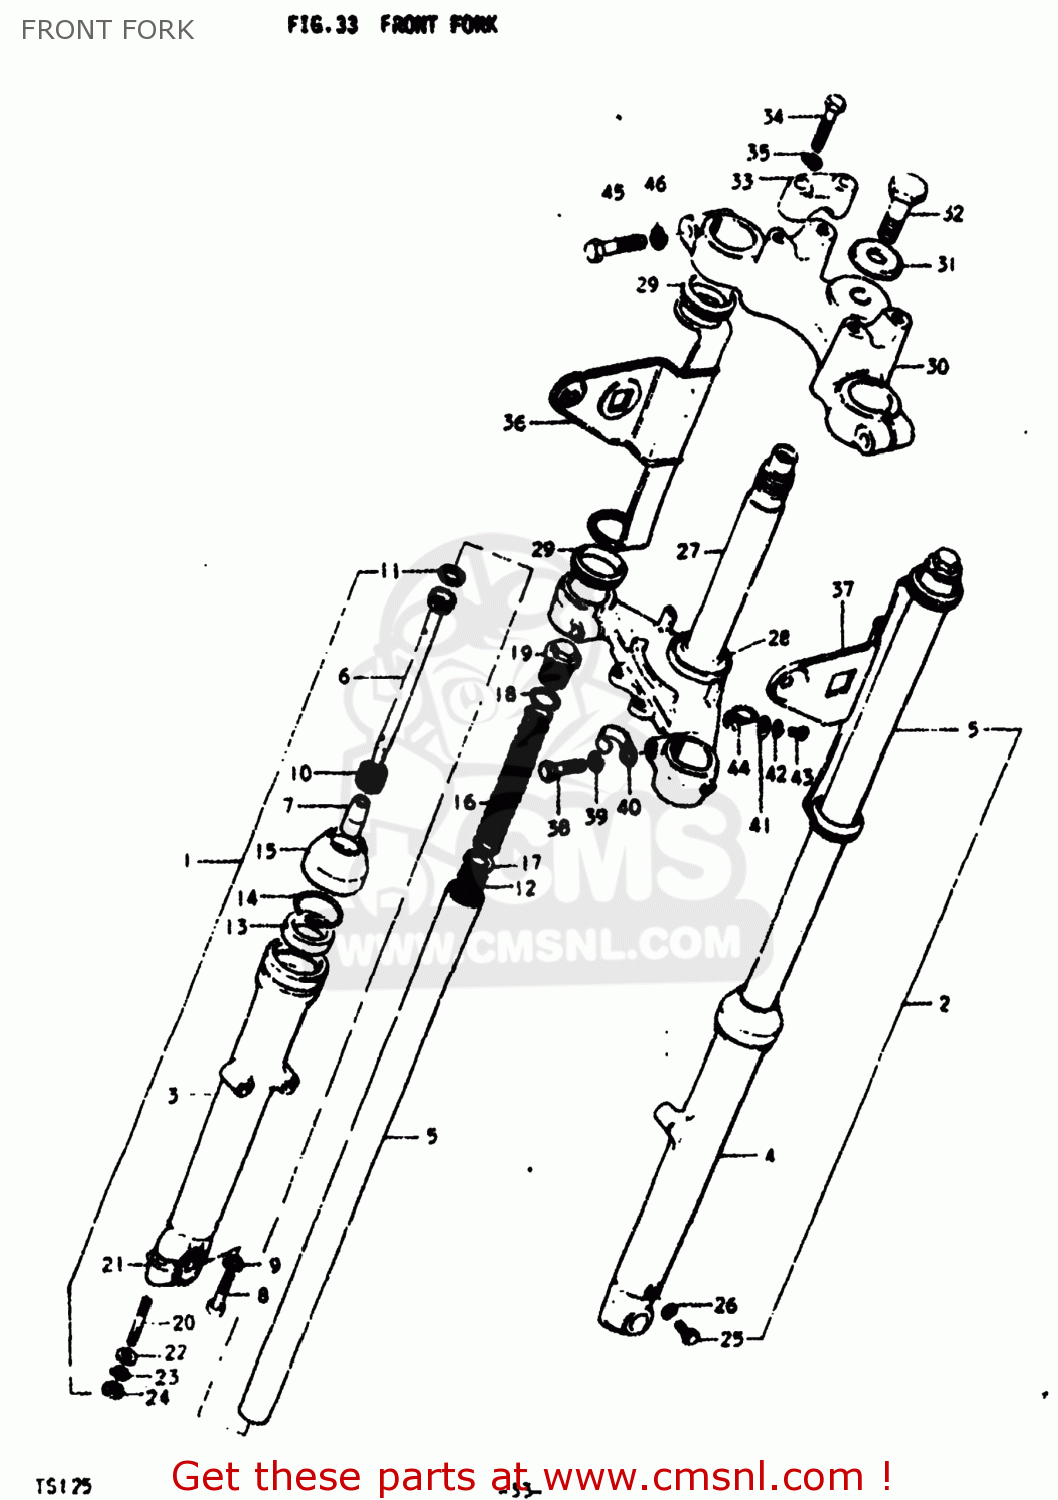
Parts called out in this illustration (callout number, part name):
1	DAMPER ASSEMBLY,RIGHT
2	DAMPER ASSEMBLY,LEFT
3	TUBE,FORK,OUTER,RIGHT
4	TUBE,FORK,LEFT,OUTER
5	TUBE,INNER
6	CYLINDER,FRONT FORK
7	PIECE,OIL LOCK
8	BOLT
9	GASKET (NAS)
10	SPRING,FORK REBOUND
11	RING
12	SPRING,FRONT FORK
13	OIL SEAL,FRONT FORK
14	CIRCLIP,FORK OIL SEAL
15	DUST SEAL,FRONT FORK
16	SPRING,FRONT FORK
17	SEAT,SPRING
18	O RING
19	BOLT,FORK
20	STUD 8X25
21	HOLDER,AXLE
22	WASHER
23	LOCK WASHER
24	NUT
25	BOLT(6X8)
26	GASKET,DRAIN,PLUG (NAS)
27	STEM,STEERING
28	RACE,STEERING OUTER LWR
29	CUSHION
30	HEAD,STEERING STEM(BLACK)
31	WASHER,STEERING STEM
32	BOLT,FORK INNER TUBE
33	HOLDER,HANDLE UPR
34	BOLT
35	LOCK WASHER
36	BRACKET,HEADLAMP,RIGHT
37	BRACKET,HEADLAMP,LEFT
38	BOLT
39	WASHER,LOCK 12
40	CLIP
41	WASHER
42	LOCK WASHER
43	SCREW 6X12
44	CLIP
45	BOLT 10X40
46	LOCK WASHER
